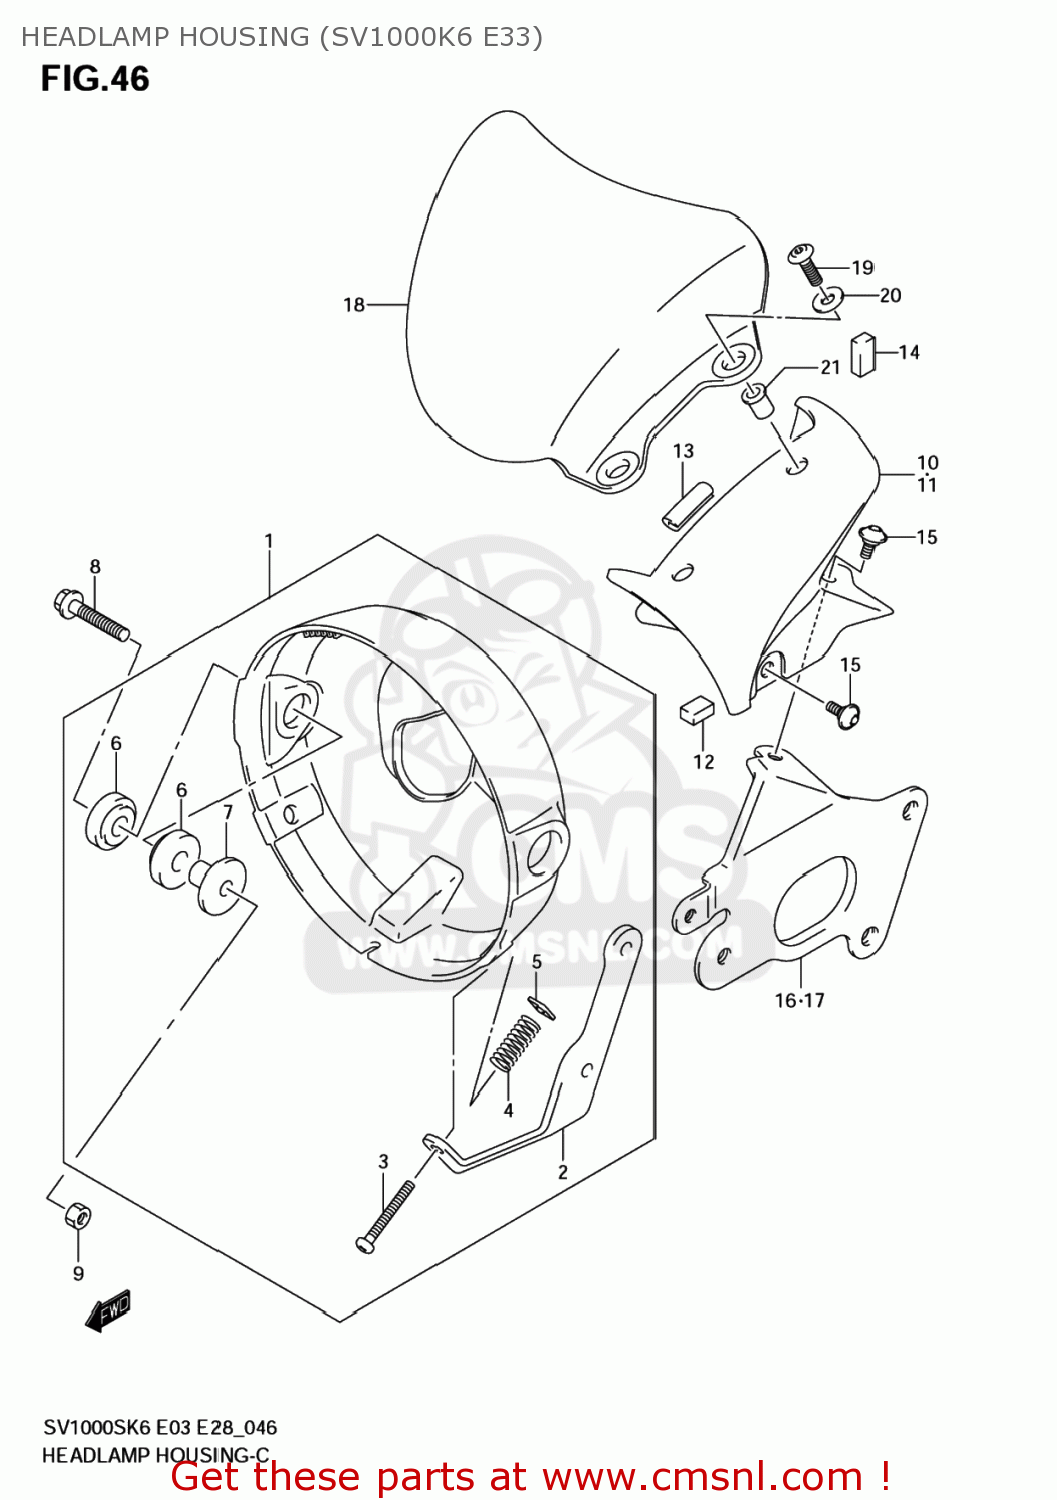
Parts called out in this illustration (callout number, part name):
1	HOUSING ASSY,HEADLAMP
2	PLATE,HEADLAMP HOUSING
3	SCREW(5X45)
4	SPRING,HEADLAMP ADJUSTER
5	NUT,HEADLAMP ADJUSTER
6	CUSHION
7	SPACER(8.6X12X21.3)
8	BOLT(8X35)
9	NUT
10	COVER,HEADLAMP HSG,R
11	COVER,HEADLAMP HSG,L
12	CUSHION,FR PANEL LID
13	MOLDING
14	TAPE
15	SCREW(5X13)
16	PLATE,HOUSING COVER,R
17	PLATE,HOUSING COVER,L
18	COVER,METER
19	SCREW(5X18)
20	WASHER
21	NUT
